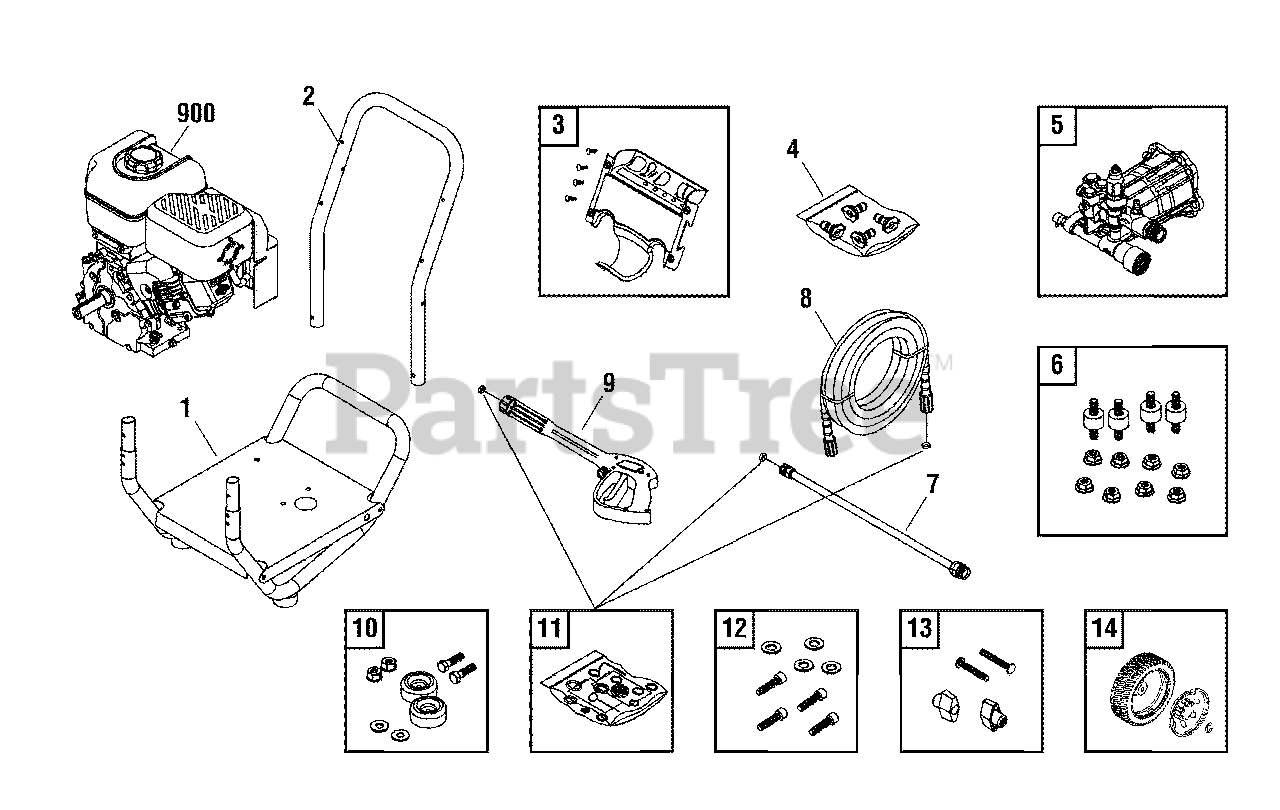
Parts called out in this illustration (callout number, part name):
5	PUMP
6	KIT, Vibration Mount
7	EXTENSION
9	GUN
10	MOUNT, Vibration
11	KIT, O-Ring
12	KIT, Hardware, Pump Mounting
13	KIT, Hardware, Handle
900	* ENGINE
